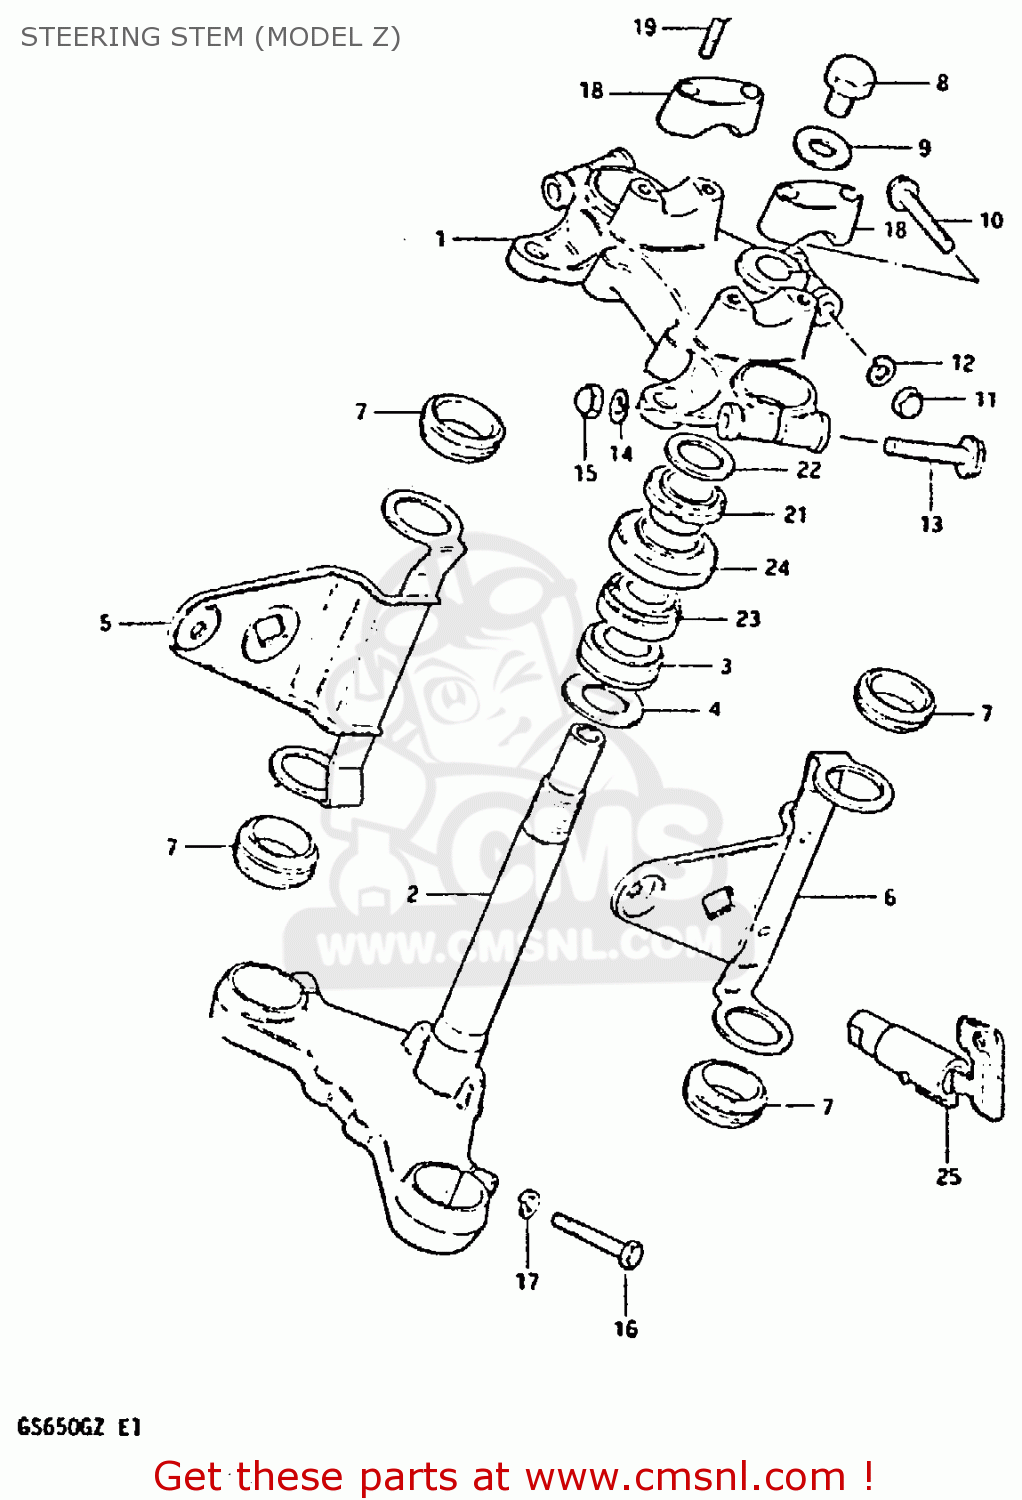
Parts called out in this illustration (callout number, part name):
1	STEM HEAD, STEERING (BLACK)
2	STEM, STEERING
3	BEARING
4	WASHER,THRUST
5	BRACKET,HEADLAMP,RIGHT
6	BRACKET,HEADLAMP,LEFT
7	CUSHION,HEADLAMP BRACKET
8	BOLT 12X20
9	WASHER (12.5X26X1.6)
10	BOLT
11	NUT,M8X1.25X12
12	LOCK WASHER
13	BOLT 10X55
14	LOCK WASHER
15	NUT
16	BOLT 10X40
17	LOCK WASHER
18	HOLDER,HANDLEBAR(BLACK)
19	BOLT
20	CAP(OD:14.5)
21	NUT,STEERING STEM
22	WASHER(18.5X24X1)
23	TAPER,ROLLER BEARING
24	DUST SEAL,STEERING UPR
